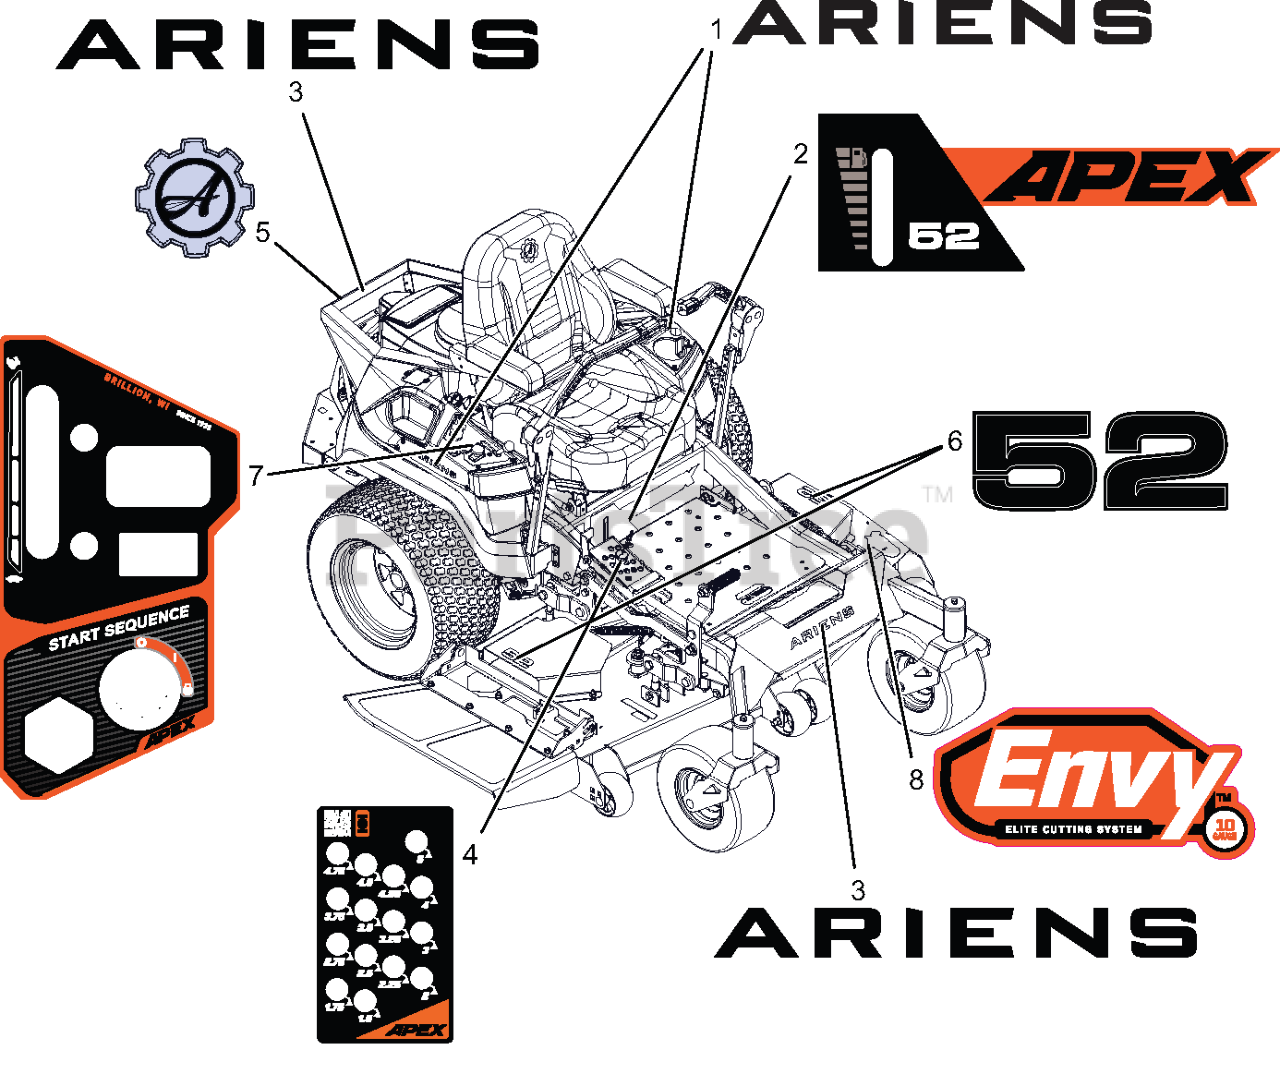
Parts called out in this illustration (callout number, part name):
1	DECAL- ARIENS 6.000" BLACK
2	DECAL- APEX 52 KICKPLATE
3	DECAL- ARIENS 9.625" BLACK
4	DECAL- APEX HOC
5	DECAL- ARIENS GEAR BADGE
6	DECAL- DECK 52
7	DECAL- DASH -APEX & ZENITH
8	DECAL- DECK -ENVY
